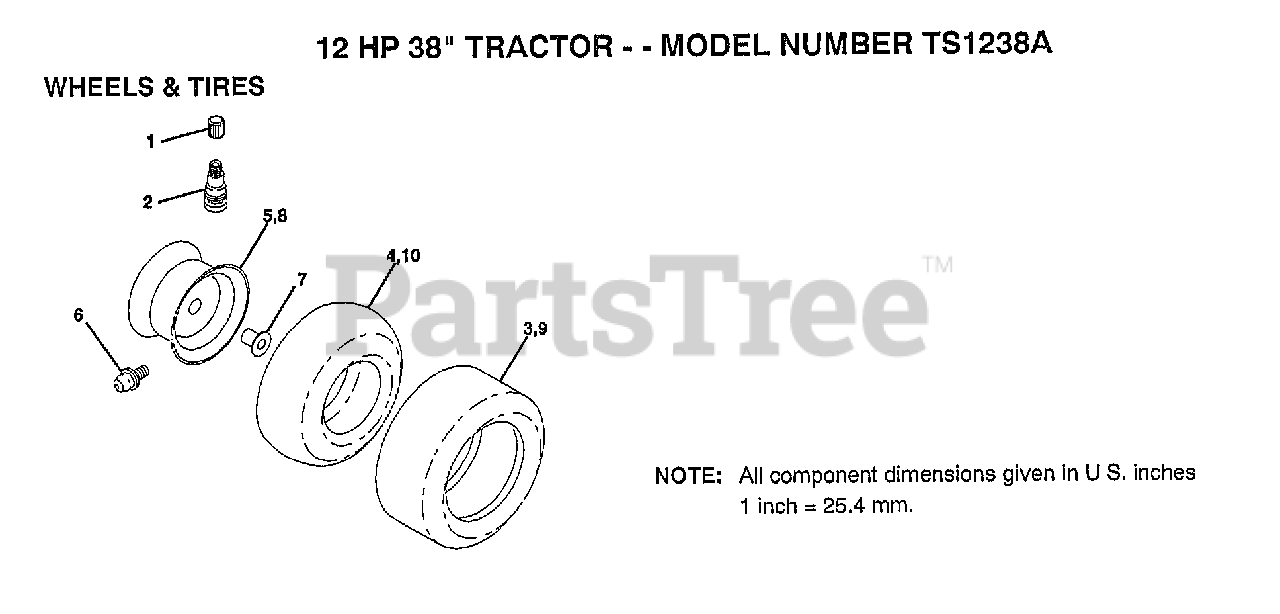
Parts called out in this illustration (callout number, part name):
1	VALVE CAP
2	VALVE STEM LT
4	TUBE.5.3/4.5/6
6	FITTING LT
7	"FLANGE, BEARING"
9	TIRE.TS2.18X8.5
10	TUBE.18X9.5-8
